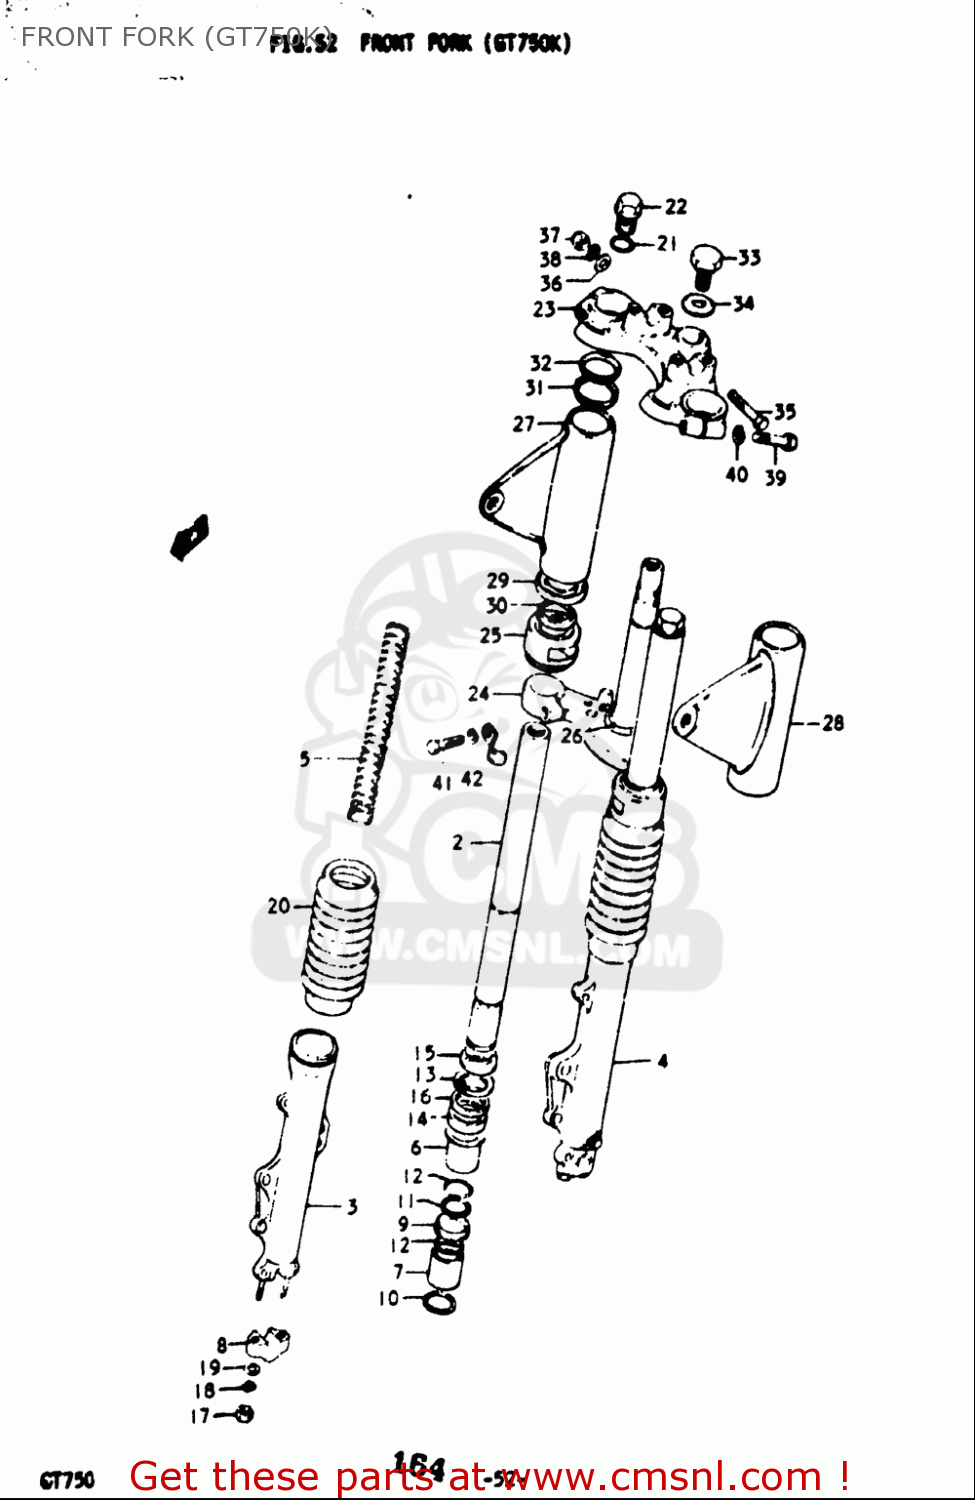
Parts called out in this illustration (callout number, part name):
8	HOLDER,AXLE
14	SEAL,OIL 35X48X11
16	RING,FR FORK
17	NUT
18	WASHER,LOCK
19	WASHER
20	BOOT
21	O RING
22	CAP,INNER TUBE
26	RACE,STEERING OUTER LWR
29	GUIDE
30	CUSHION,HEADLAMP BRACKET
31	GUIDE
32	CUSHION,HEADLAMP BRACKET UPR
35	BOLT
36	WASHER
37	NUT
38	WASHER,LOCK
39	BOLT
40	WASHER,LOCK
41	BOLT
42	WASHER,LOCK
